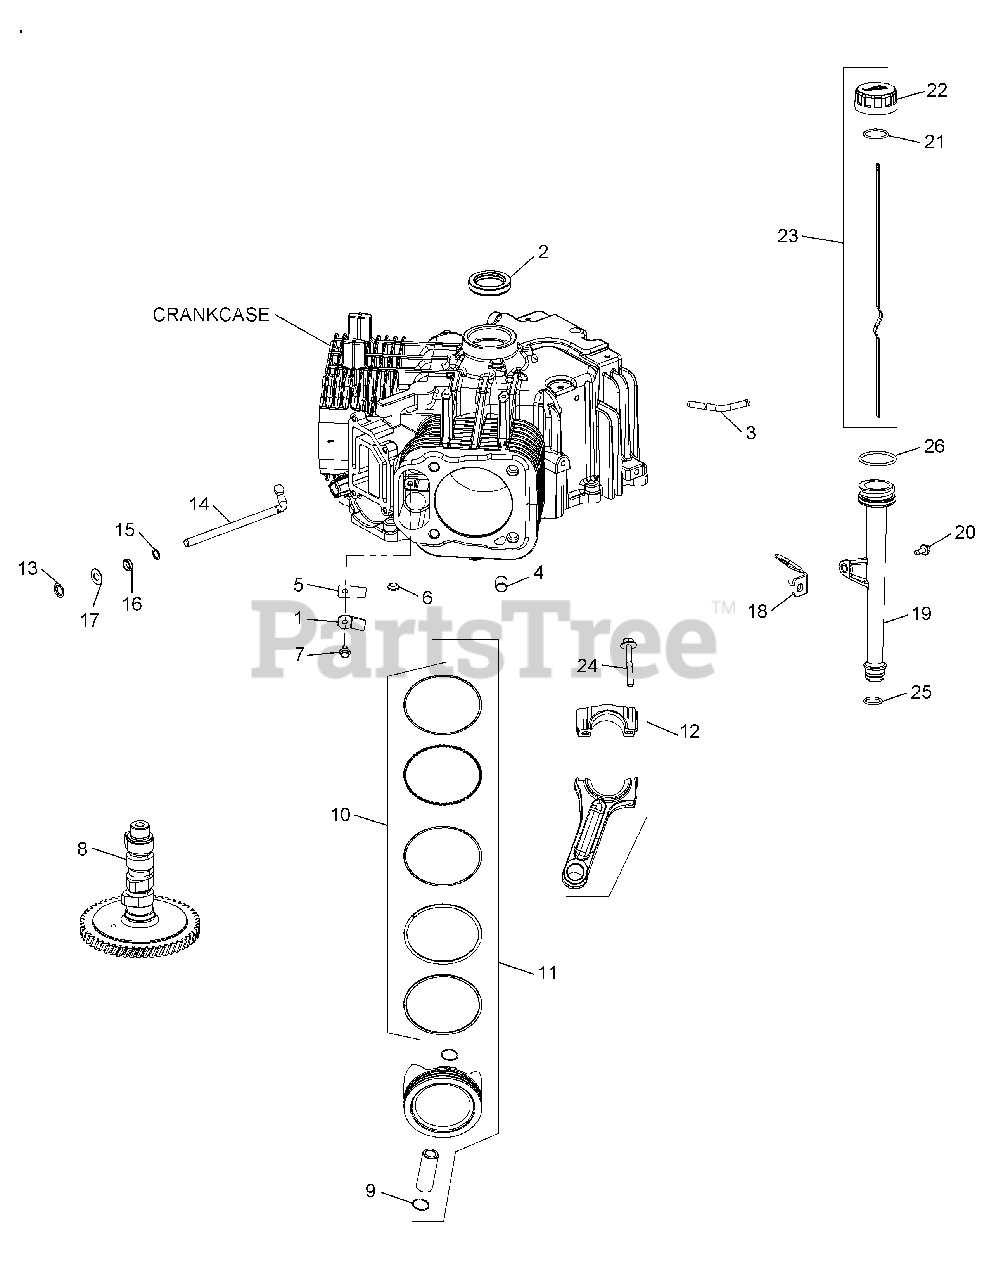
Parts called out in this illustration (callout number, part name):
1	Breather Reed Retainer
5	Breather Reed
7	Flange Screw, M5 x 0.8 x 10
9	Piston Pin Retainer
10	Piston Ring Set (STD)
10	Piston Ring Set (.08)
10	Piston Ring Set (.25)
10	Piston Ring Set (.50)
11	Piston Kit w/ Ring (STD) (Inc. 9 & 10)
11	Piston Kit w/ Ring (.08)
11	Piston Kit w/ Ring (.25)
11	Piston Kit w/ Ring (.50)
12	Connecting Rod Kit (Inc. 24)
13	Ring Retainer
14	Governor Cross Shaft
15	Flat Washer, 11/32"
16	Governor Cross Shaft Seal
17	Flat Washer, 9 mm
18	Oil Fill Tube Bracket
19	Oil Fill Assembly Tube
20	Flange Screw, M5 x 0.8 x 13
21	Dipstick O-Ring
22	Oil Fill Cap Kit (Yellow)
23	Dipstick, Assembly (Inc. 21 & 22)
24	Connecting Rod Bolts Kit
25	Lower Oil Fill Tube O-Ring
26	Upper Oil Fill Tube O-Ring
